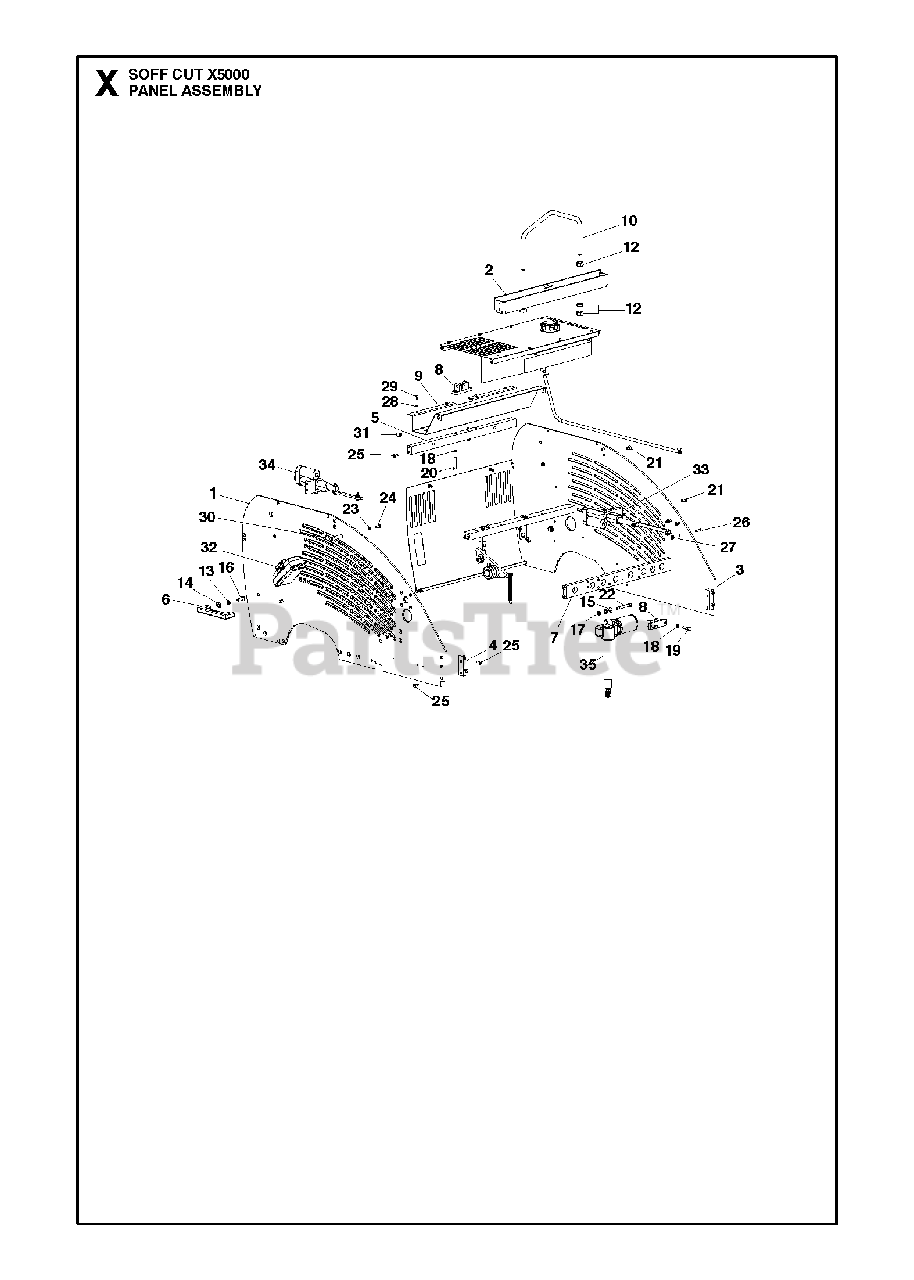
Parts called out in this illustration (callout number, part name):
4	BLOCK. PANEL CORNER MOUNT
19	5/16-18 X 1 3/4 HEX BOLT GRD5
26	NUT
